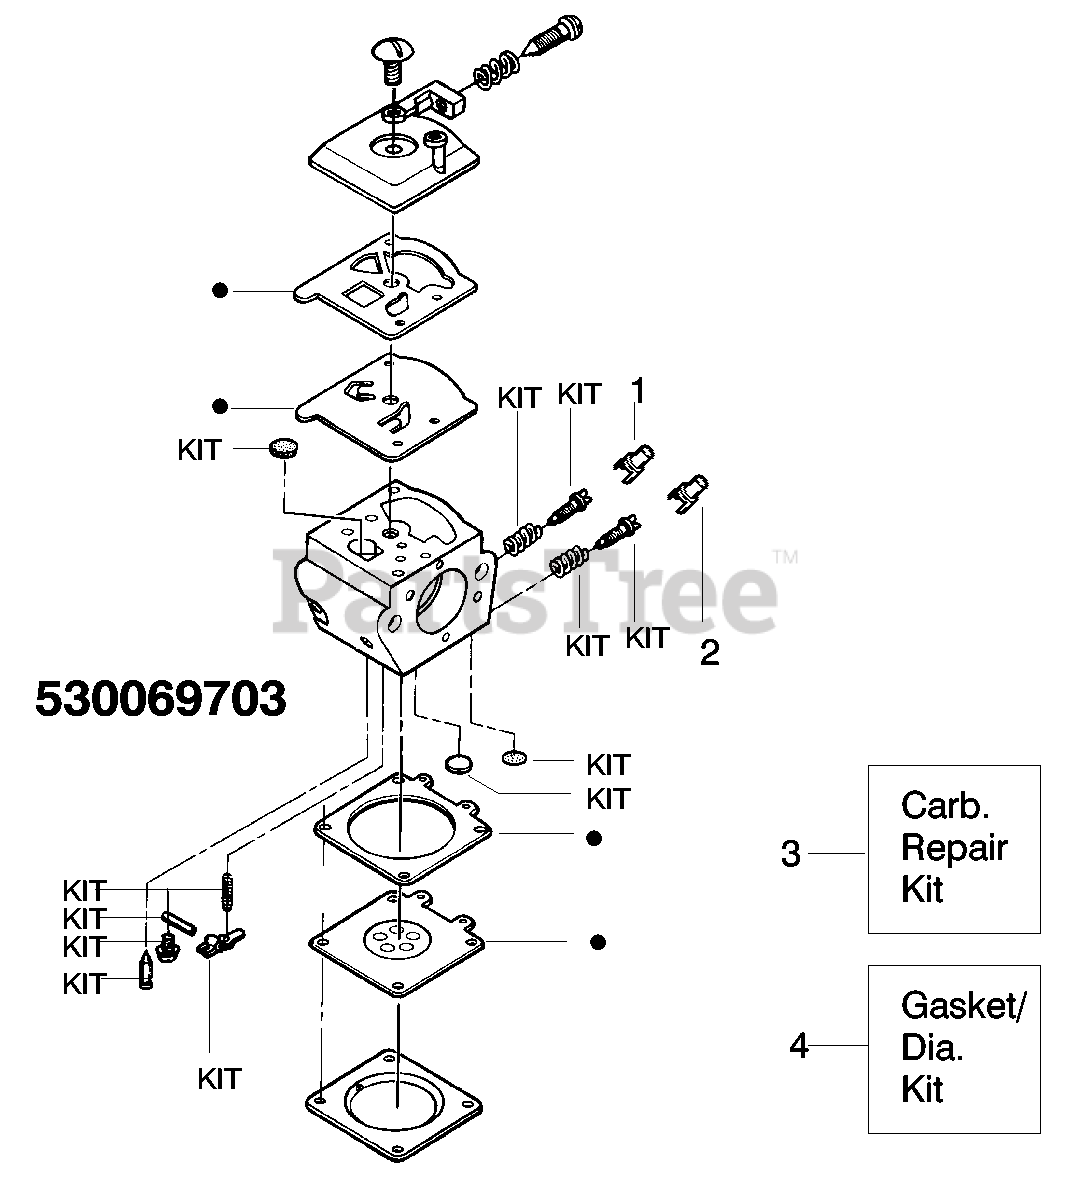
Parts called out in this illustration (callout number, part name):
1	Limiter Cap-High (brown)
2	Limiter Cap-Low (tan)
3	Carburetor Repair Kit - Walbro (WT324)
4	Gasket Diaphragm Kit - Walbro (WT324)
530069703	Carburetor Assembly - Walbro-WT324
